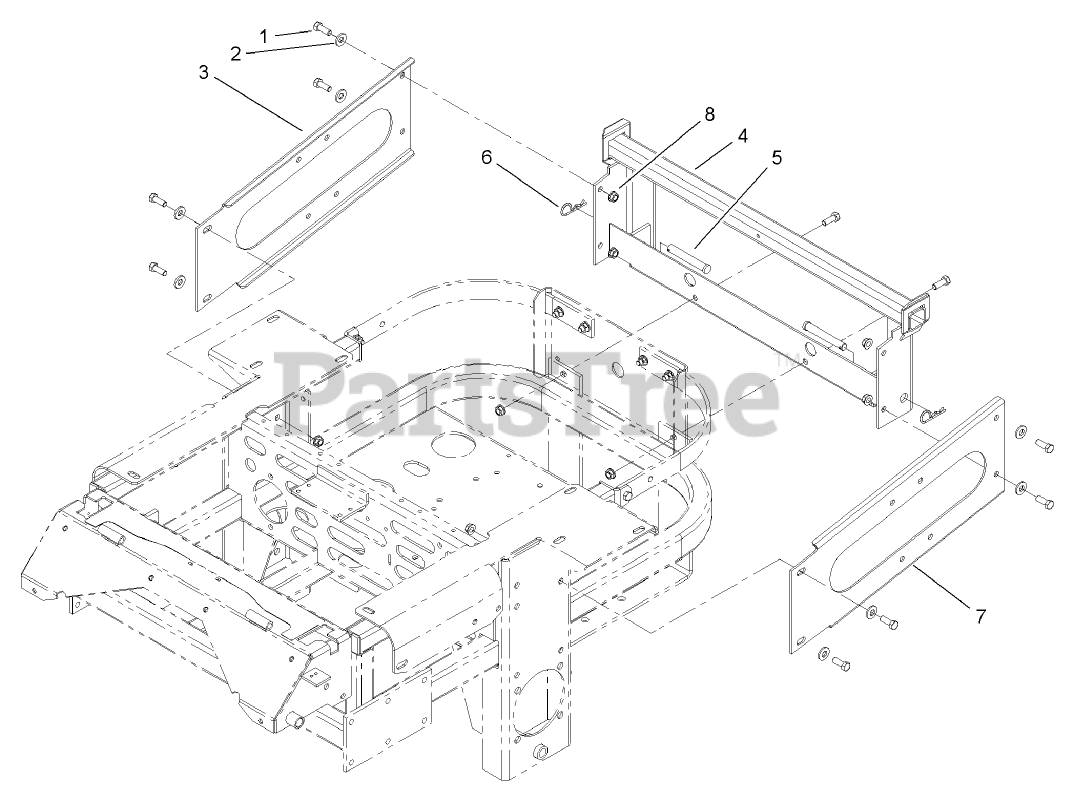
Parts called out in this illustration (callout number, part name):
1	SCREW-HH
2	WASHER-BELLEVILLE
3	BRACKET-FRAME, RH
4	MOUNT-BAGGER
5	PIN-CLEVIS
6	PIN-COTTER
7	Bracket-Frame, LH
8	NUT-HHF, WHIZ
